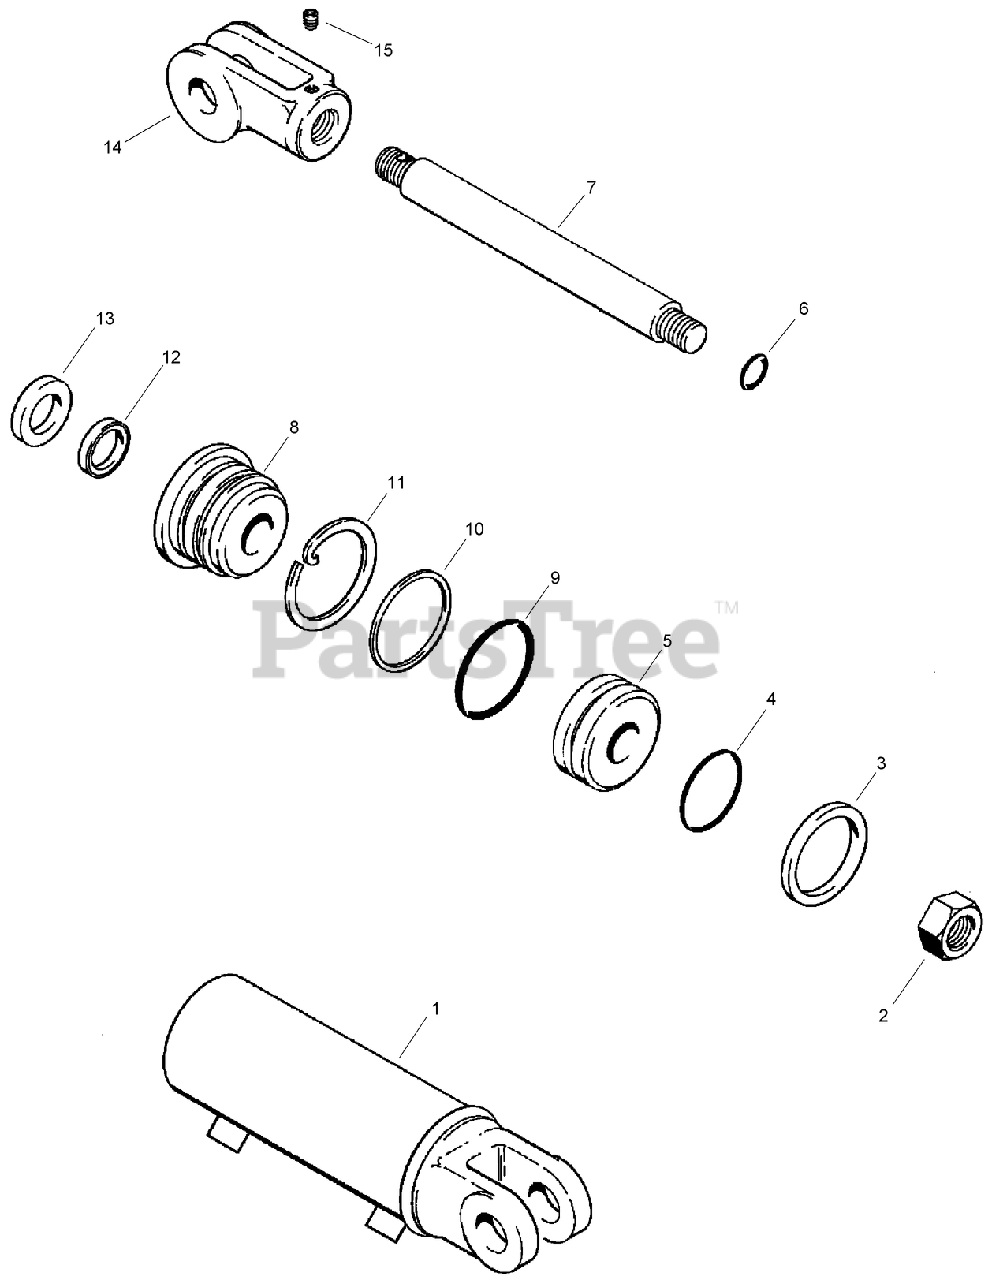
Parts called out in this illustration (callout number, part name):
1	TUBE-cylinder
2	NUT-hex, self-locking, 3/4 inch NF
3	Seal-Piston
4	O-RING-piston
5	PISTON-cylinder
6	O-RING-piston rod
7	ROD-piston
8	GLAND-cylinder
9	O-RING-gland
10	RING-backup, gland O-ring
11	WIRE-locking, gland
12	SEAL-U-cup, gland
13	WIPER-piston rod
14	CLEVIS-piston rod
15	SCREW-set, hex socket headless, 5/16 NC x 3/8 inch, cup point
